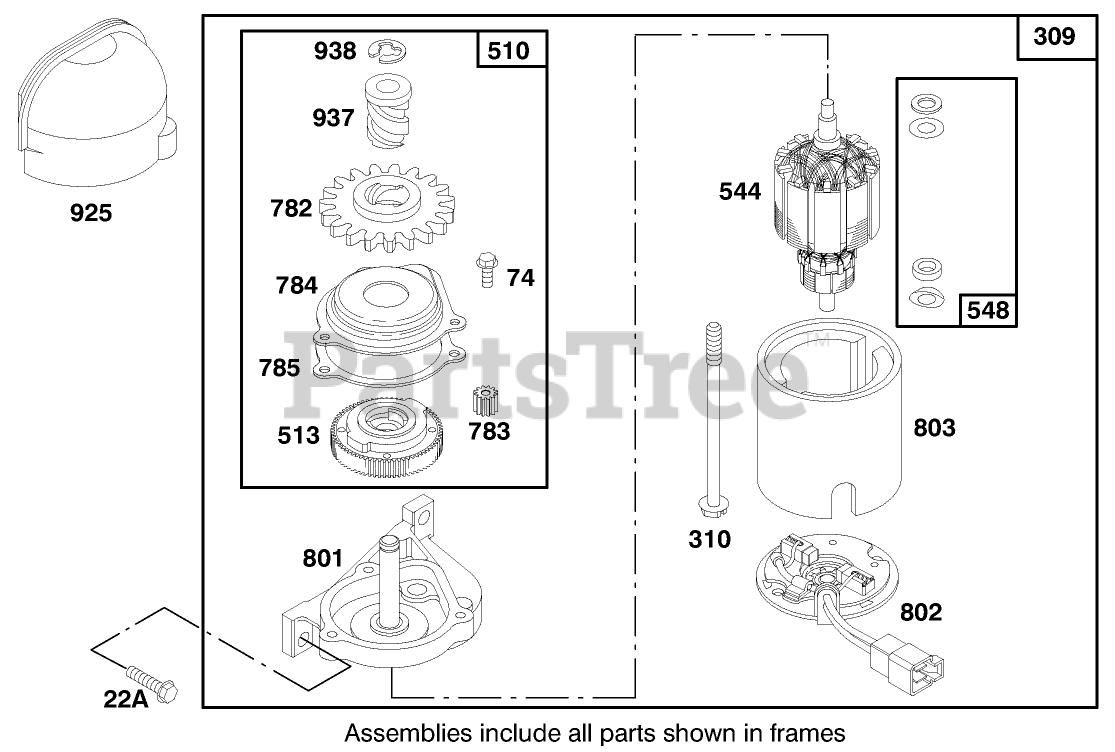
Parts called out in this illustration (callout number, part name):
22A	SCREW - CARBUERTOR MTG
510	DRIVE SET
513	CLUTCH - STARTER
548	WASHER ASSEMBLY
782	GEAR - STARTER
925	COVER - STARTER
938	RETAINER - LOCK
